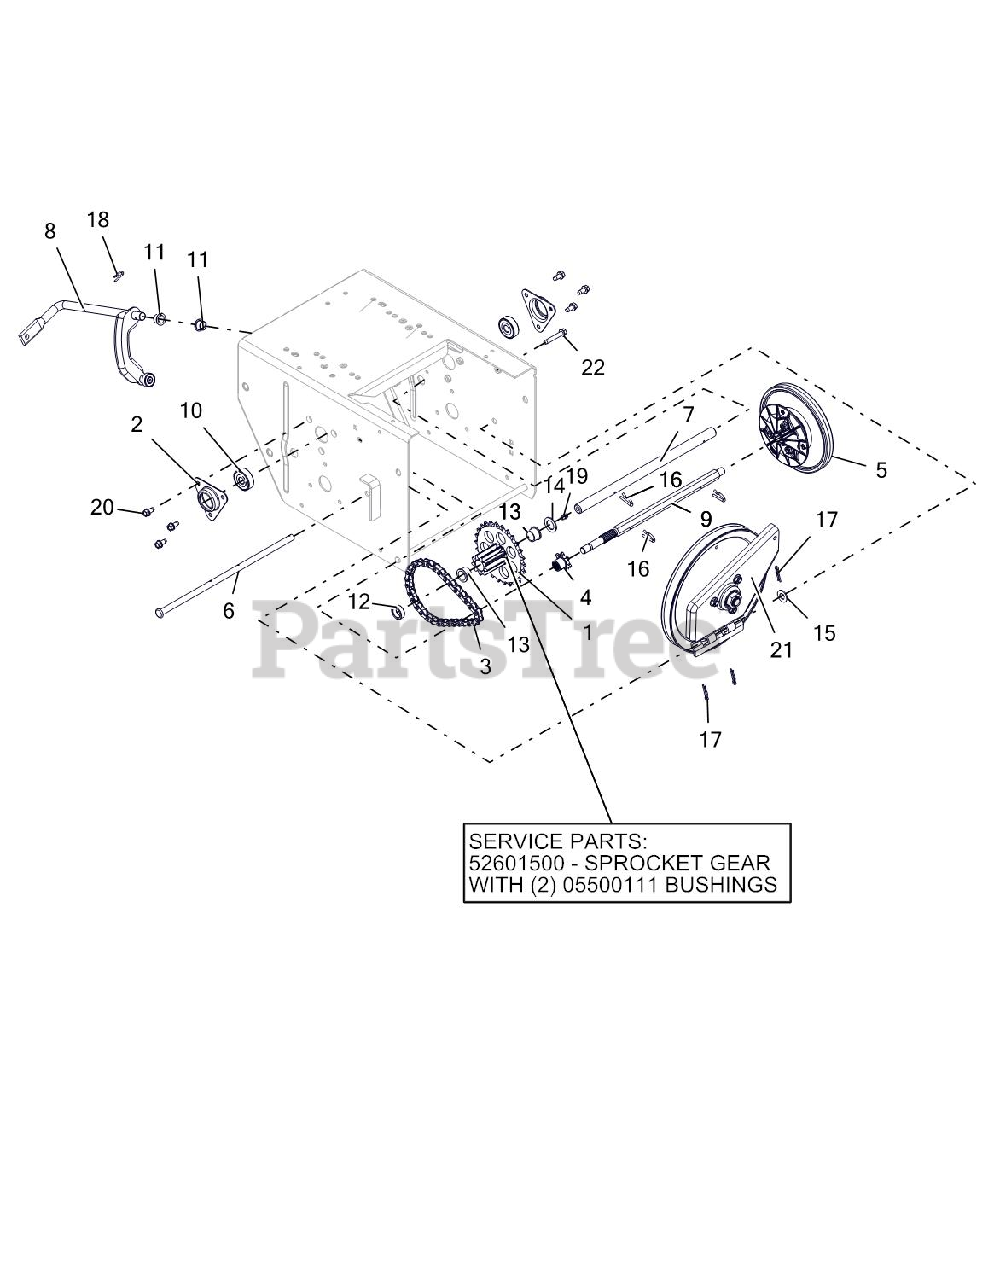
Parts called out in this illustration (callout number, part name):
1	BSHG-FLG .625X.750X.500X.875
1	PINION & SPROCKET
1	PINION & SPROCKET W/BUSHINGS
2	FLANGE, BEARING
3	CHAIN - #41, 32 PITCHES
4	SPROCKET, PINION 7T W/SPLINE
5	DISC, FRICTION DRIVE-ASSEMBLY
6	PIN, PIVOT
7	SHAFT, PINION
8	ARM, SHIFT - ASSEMBLY
9	SHAFT, HEX
10	BRG-BALL .437X1.375X.437
11	BUSHING, POLYLINER-.50 SPLIT
12	BSHG-SLV, .635X.880X.305
13	BSHG-FLG .625X.750X.500X.875
14	WSHR-FL-STL .630X1.005X.062 YZ
15	@WSHR-FL-STL.406X.812X.065 YWZ
16	PIN, SPRING CLIP
17	PIN-HAIR, ENDRIES #25 YWZC
18	CLIP, SPRING
19	ZERK,FITTING .25X.125 DRIVE IN
20	SCR-TAP .25-20X.50 HWH TR YWZ
21	PLATE, SWING ASSEMBLY-DEEP
22	@SCR-TAP .25-20X1.50 HWH TR YZ
